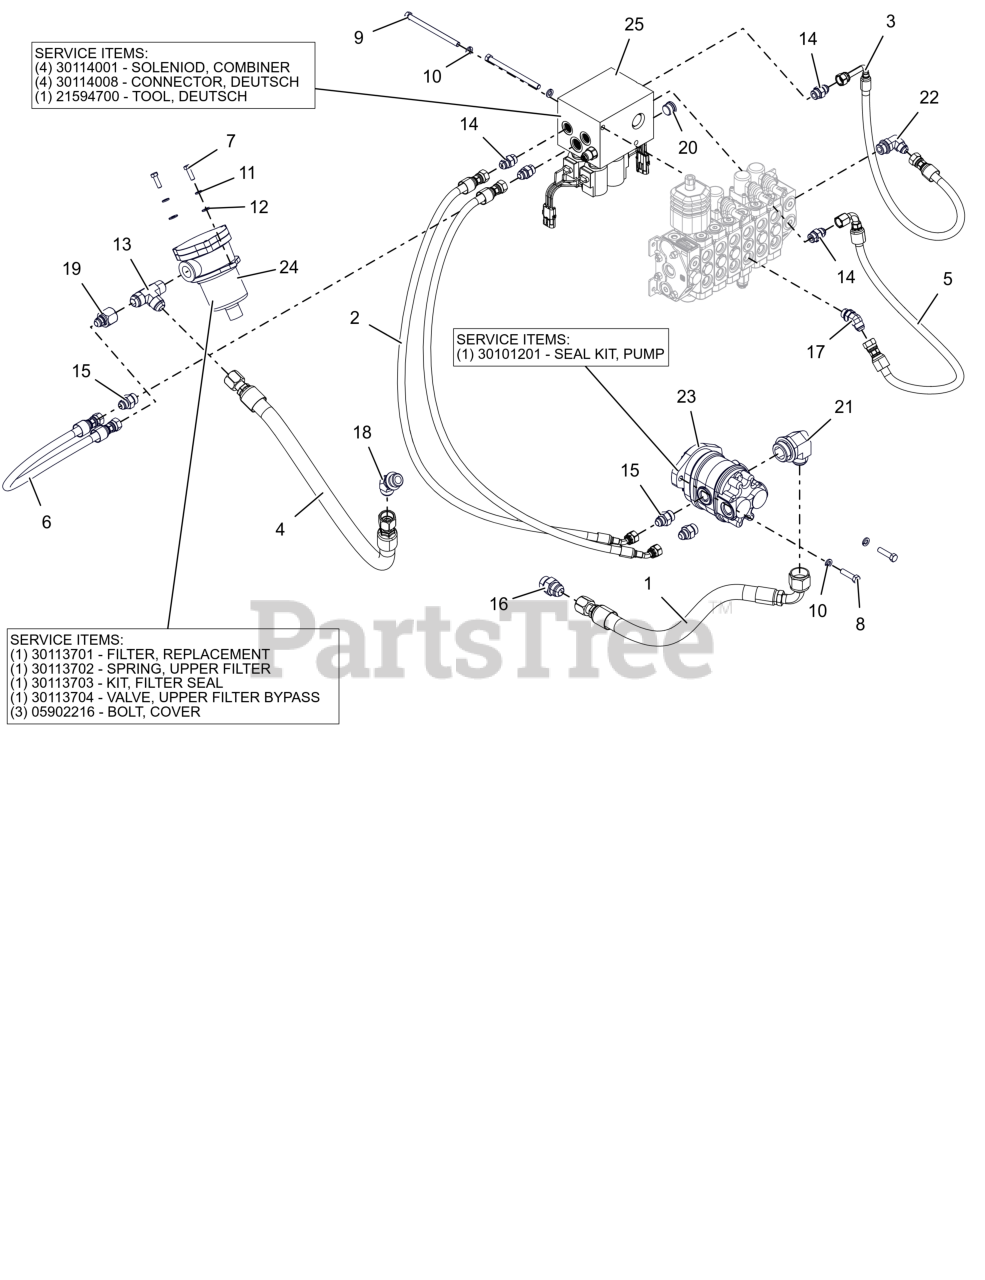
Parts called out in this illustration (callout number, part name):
1	HOSE, HYD .750" X 26.50" LG
2	HOSE, HYD .375" X 58.25" LG
3	HOSE, HYD .375" X 21.75" LG
4	HOSE, HYD .750" X 44.75" LG
5	HOSE, HYD .375" X 24.25" LG
6	HOSE, HYD FJIC-8-6 FJIC-8-6 32
7	BLT,HEX .31-18X1.00 G5 ZCC
8	BLT, HEX 0.375-16X1.5 GR8 ZCC
9	BLT, HEX 0.375-16X5.5 GR8 ZCC
10	WSHR,LK-REG .375X.094 ZCC
11	WSHR,LK-REG .312X.078 ZCC
12	WSHR, FLT .312X.734X.065 ZCC
13	BLT-SHLDR .375X4.50X.31-18
14	FITTING, HYDRAULIC 6400 8-8
15	FITTING, HYDRAULIC 6400 8-10
16	FITTING, HYDRAULIC 6400 12-12
17	FITTING, HYDRAULIC - 6802 8-8
18	FITTING, HYDRAULIC 6802 12-12
19	FITTING, HYD FJIC-12 MJIC-8
20	PLUG, HEX - CSK .875 ORB
21	FITTING, HYDRAULIC 6801 16-20
22	FITTING, HYDRAULIC - 6801 8-10
23	SEAL KIT, PUMP
24	FILTER, HYD - INTANK
24	FILTER- REPLACEMENT
24	SPRING- UPPER FILTER
24	KIT- FILTER SEAL
24	VALVE- UPPER FILTER BYPASS
24	BOLT, FOR COVER
25	VALVE, HYD - COMBINER ASSY
25	VALVE, COMBINER
25	SOLENIOD, COMBINER
25	CONNECTOR, DEUTSCH
25	TOOL, DEUTSCH
